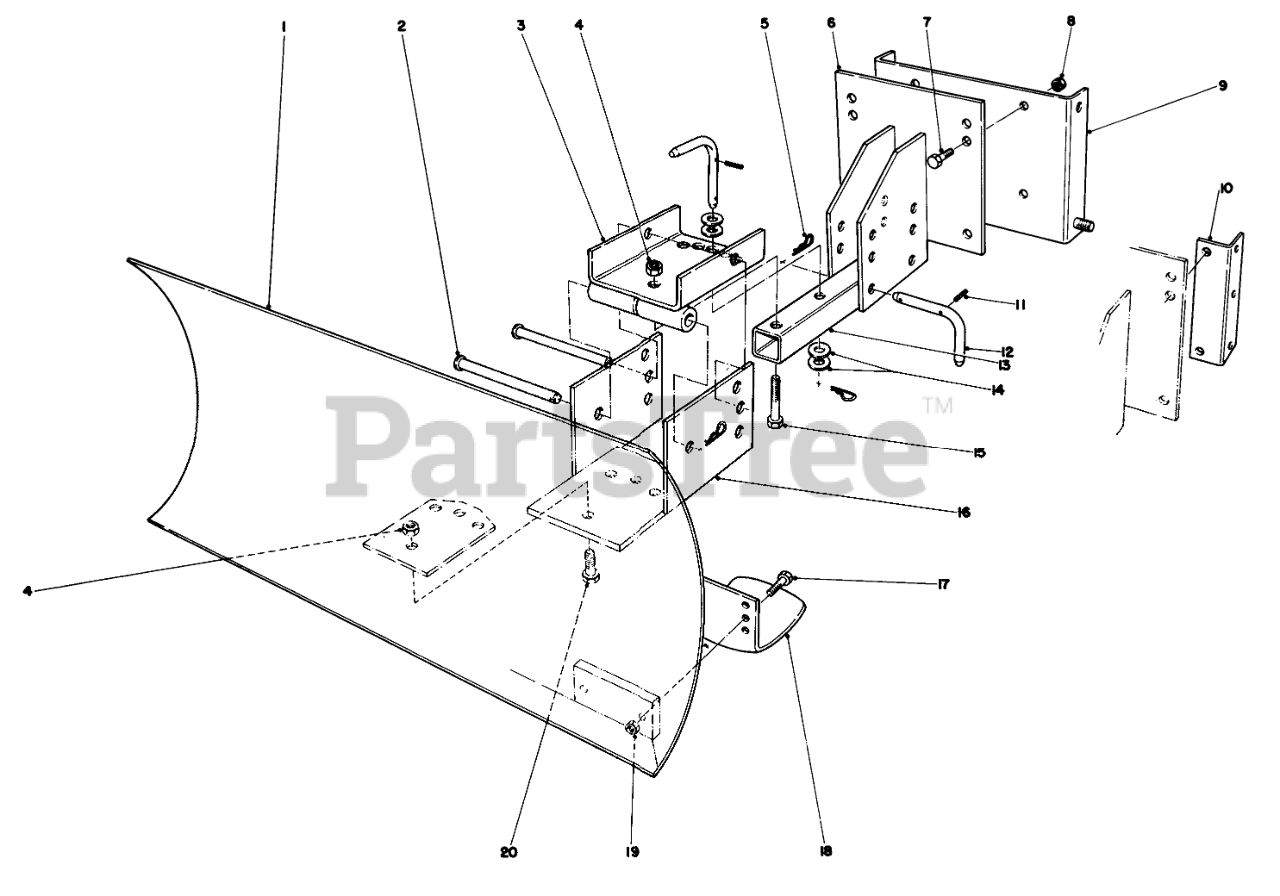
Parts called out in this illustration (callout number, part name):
1	Blade
2	PIN-CLEVIS
3	Swivel Bracket
4	1/2-13 CONELOCK NUT
5	PIN-HAIR
6	Mounting Plate
7	SCREW-HH
8	NUT-LOCK, CONE
9	Mounting Plate (Used with 826 & 1132 Units only)
10	Mounting Rail (used with 421 units only)
11	PIN-SPRING
12	Pivot Pin (Incl. Ref. #11)
13	Blade Tongue
14	WASHER-FLAT
15	SCREW-HH
16	Blade Adjustment
17	SCREW-HH
19	NUT-LOCK, CONE
20	SCREW-HH
